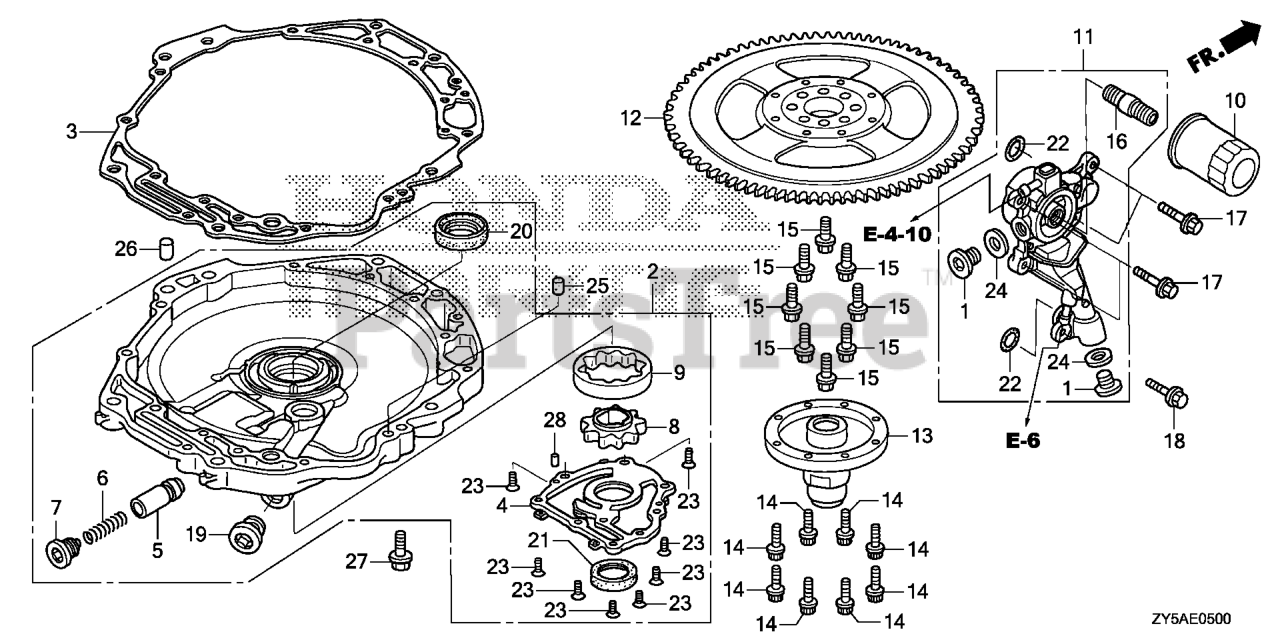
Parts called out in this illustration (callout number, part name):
1	BOLT, SEALING (20MM)
2	PUMP ASSY., OIL *NH8* (DARK GRAY)
2	PUMP, OIL *NH8*
3	GASKET, OIL PUMP BODY
4	COVER, OIL PUMP
5	VALVE, RELIEF
6	SPRING, RELIEF VALVE
7	BOLT, SEALING (18MM)
8	ROTOR, OIL PUMP (INNER)
9	ROTOR, OIL PUMP (OUTER)
10	FILTER, OIL (FILTECH TOYO ROKI) (SOLD IN MULTIPLES OF 30)
10	FILTER, OIL
11	FLANGE COMP *NH8*
12	FLYWHEEL *TBLACK* (BLACK)
13	BOSS, FLYWHEEL
14	BOLT, SPECIAL (8MM)
15	BOLT, FLANGE (12MM)
16	HOLDER, OIL FILTER
17	BOLT, FLANGE (6X25)
18	BOLT, FLANGE (6X20)
19	BOLT, SEALING (22MM)
20	OIL SEAL (46X60X9)
21	OIL SEAL (31X46X7) (NOK)
22	O-RING (22.5X2.4)
23	SCREW, FLAT (6X16) (YAMADA)
24	WASHER, DRAIN PLUG (20MM)
25	PIN A, DOWEL (10X16)
26	PIN A, DOWEL (14X20)
27	BOLT, FLANGE (8X32)
28	ROLLER (5X8)
